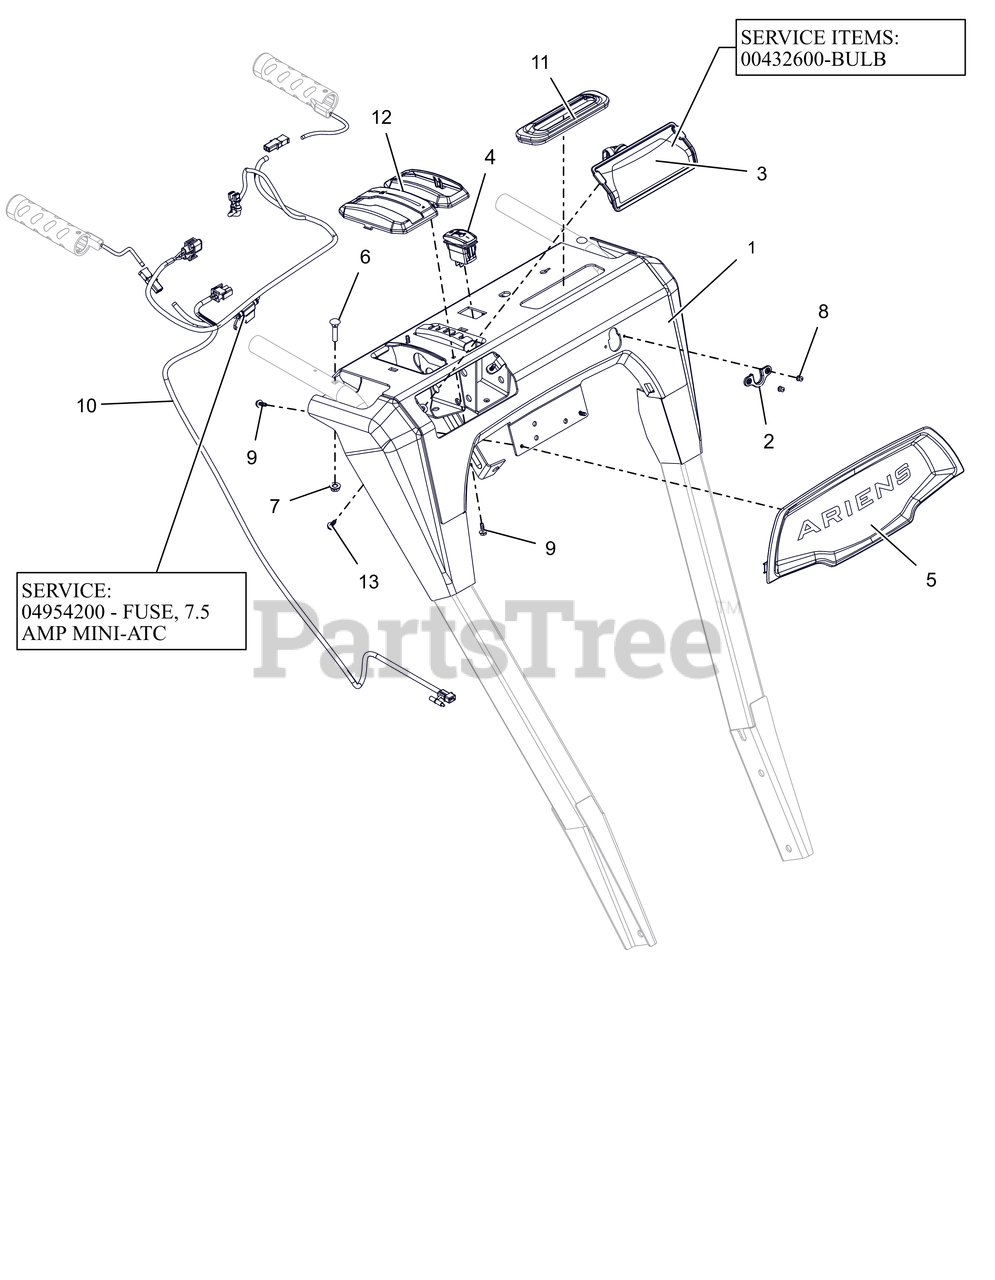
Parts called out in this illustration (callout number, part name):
1	PANEL, DASH-HYDRO EFI W/DECAL
2	GROMMET, CABLE, QUICK TURN 2
3	HEADLIGHT ASY, HALO 20W 2SHOT
3	BULB, LIGHT-HALOGEN 20W
4	SWITCH,ROCKER SPST-ON/OFF
5	BEZEL, DASH - ARIENS LG DASH
6	BLT-RDHDXLSQNK.25-20X1.25 G5ZC
7	@NUT-LK-CTR-FLG .25-20 YWZC
8	RVT-POP #43 .125X.313 STL ZINC
9	SCR-TAP #10X.50 BOSS INDHXHD
10	HARNESS,LIGHT&WARMER - EFI
10	FUSE, 7.5 AMP MINI-ATC
11	GROMMET, BOOT, QUICK TURN
12	BEZEL, SHIFT - HYDRO SNOW
13	SCR-TAP #10X.50 BOSS INDHXHD
